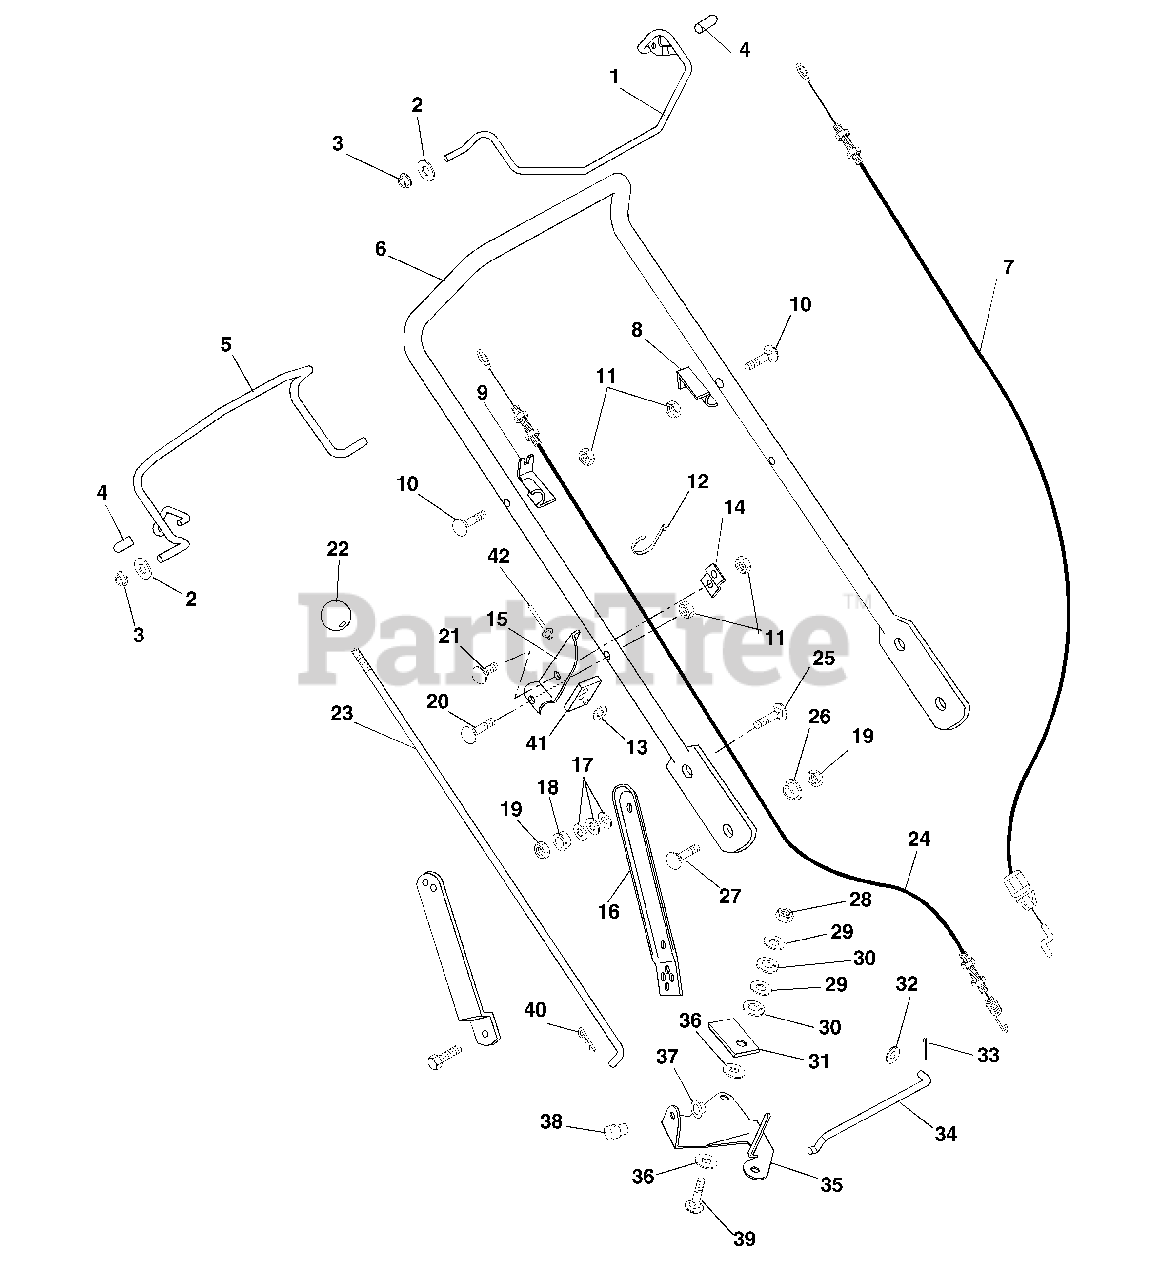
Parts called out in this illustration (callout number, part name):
1	ENGINE BAIL
2	@WSHR-FL-STL.344X.688X.065YWZC
3	BSHG-FLG .325X.444X.440X.560
4	CAP, VINYL, .25 ID
5	TRACTION BAIL
6	HANDLEBAR
7	ENGINE CONTROL CABLE
8	CABLE ANCHOR-LH
9	CABLE ANCHOR, RH
10	BLT-RDHDXLSQNK.25-20X1.25 G5ZC
11	@NUT-LK-CTR .25-20 YWZC
12	CABLE TIE LG 5-1/2
13	@WSHR-FL-STL.219X.50X.049 YWZC
14	BRACE, SPEED CONTROL
15	BRACKET, SPEED CONTROL
16	LINK, HANDLEBAR ADJUSTMENT LH
16	LINK, HANDLEBAR ADJUSTMENT RH
17	WASHER, BELLEVILLE YWZC
18	BSHG-FLG .325X.500X.513X.875
19	@NUT-LK-CTR .31-18 YWZC
20	@BLT-RDHDSQNK .25-20X1.50 G5YZ
21	@BLT-RDHDSQNK .25-20X.50 G5YZ
22	KNOB, BALL 5/16-18 X 1.5
23	ROD-SPEED CONTROL
24	TRACTION CABLE
25	@BLT-RDHDSQNK .31-18X1.00 G5YZ
26	BSHG, FLG .325X.499X.26X.88
27	@BLT-RDHDSQNK .31-18X.75 G5YZ
28	@NUT-LK-CTR .38-16 YWZC
29	@WSHR-FL-STL.406X.812X.065 YWZ
30	WSHR-LK .375X.115 HVY YWZC
31	PRESSURE FLANGE
32	@WSHR-FL-STL.281X.62X.065 YWZC
33	@PIN-CTR .06X.50 EXTPRSQCT YWZ
34	SHIFT LINK
35	BELL CRANK - SPEED CONTROL
36	FRICTION WASHER
37	CAP, 3/8 ROD YWZC
38	SWIVEL
39	@BLT-RHDSSQNK .38-16X1.25 G5YZ
40	PIN-HAIR INT .08X.18X1.18 YWZC
41	SUPPORT PAD
42	RVT .187X.575 DOME AL BLACK
